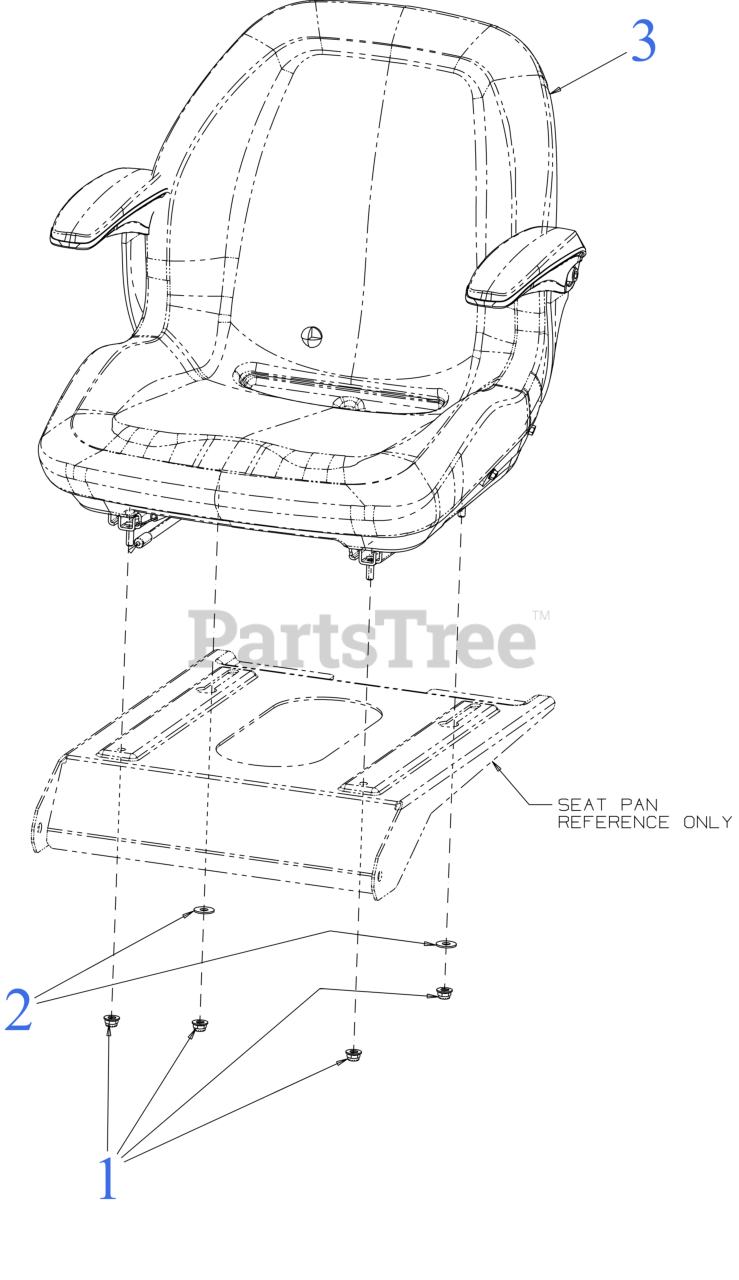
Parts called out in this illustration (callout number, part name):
1	FLANGE LOCK NUT 5/16-18
2	FLAT WASHER
3	SEAT (CRAFTSMAN/SLIDE/ARM)
